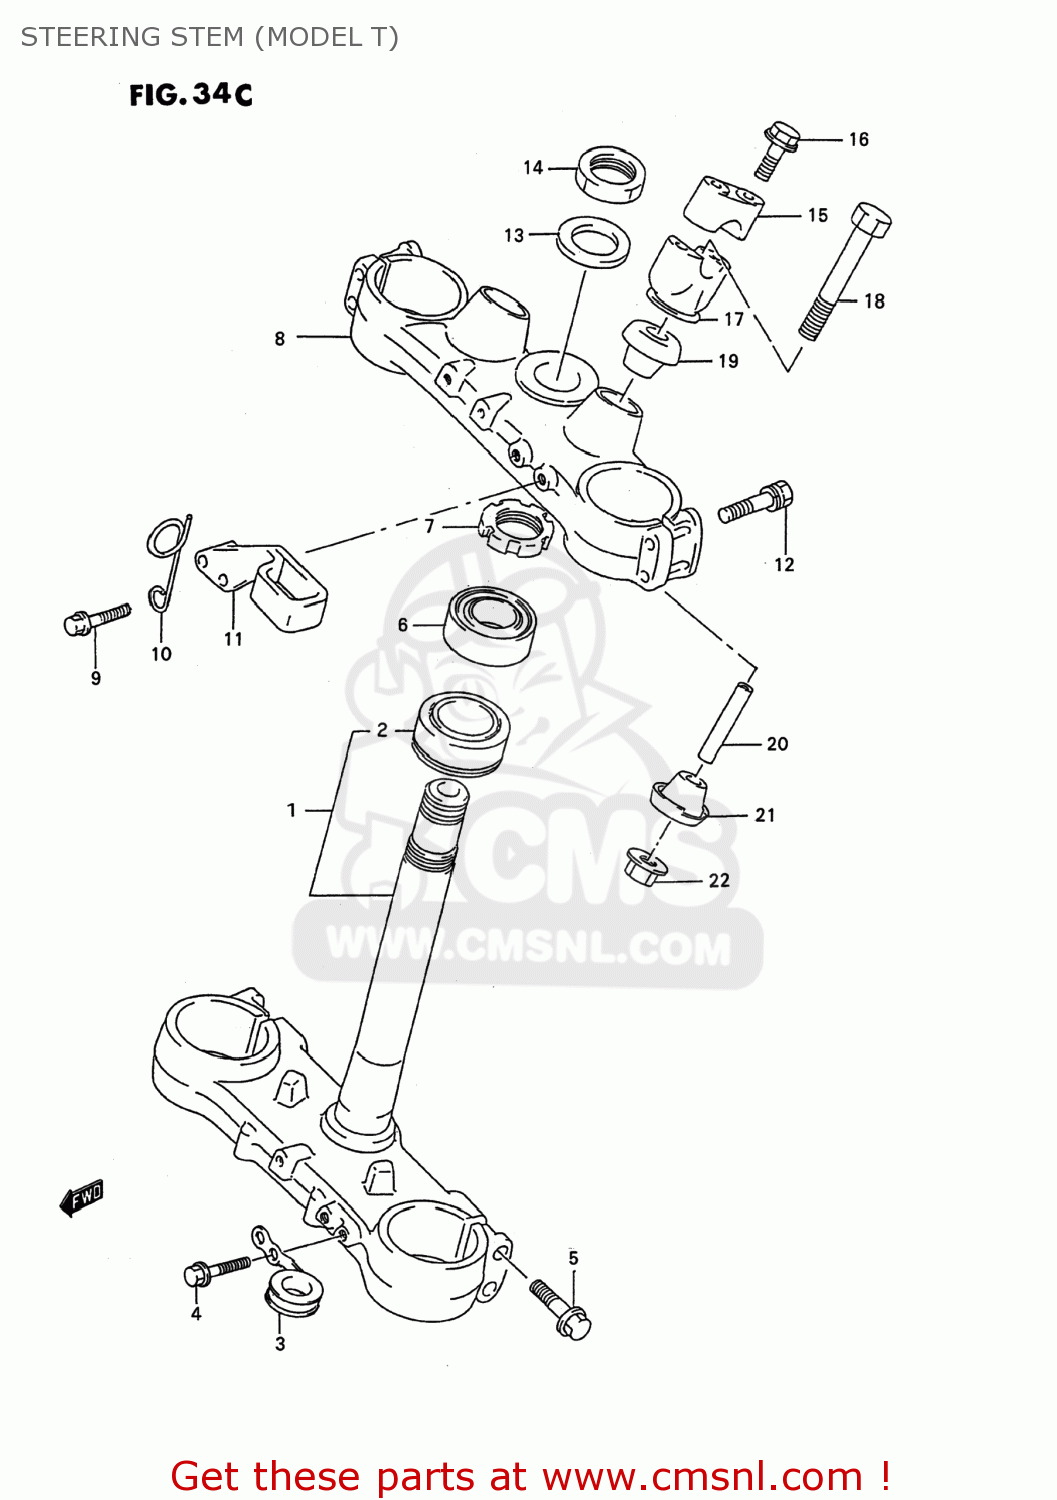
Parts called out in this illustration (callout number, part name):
1	STEM,STEERING
2	BEARING(30X52X16)
3	GUIDE,CABLE LWR
4	BOLT,PROTECTOR(6X10)
5	BOLT
6	BEARING(30X52X16)
7	NUT,STEERING
8	HEAD,STEERING STEM
9	BOLT,GUIDE
10	GUIDE,CLUTCH CABLE
11	GUIDE,HOSE
12	BOLT
13	WASHER,STEM HEAD
14	NUT,STEM HEAD
15	HOLDER,HANDLEBAR
16	BOLT,HANDLE HOLDER(8X35)
17	HOLDER,HANDLE UNDER
18	BOLT,HANDLE HOLDER(10X70)
19	CUSHION,RUBBER UPR
20	SPACER
21	CUSHION,RUBBER UNDER
22	NUT
